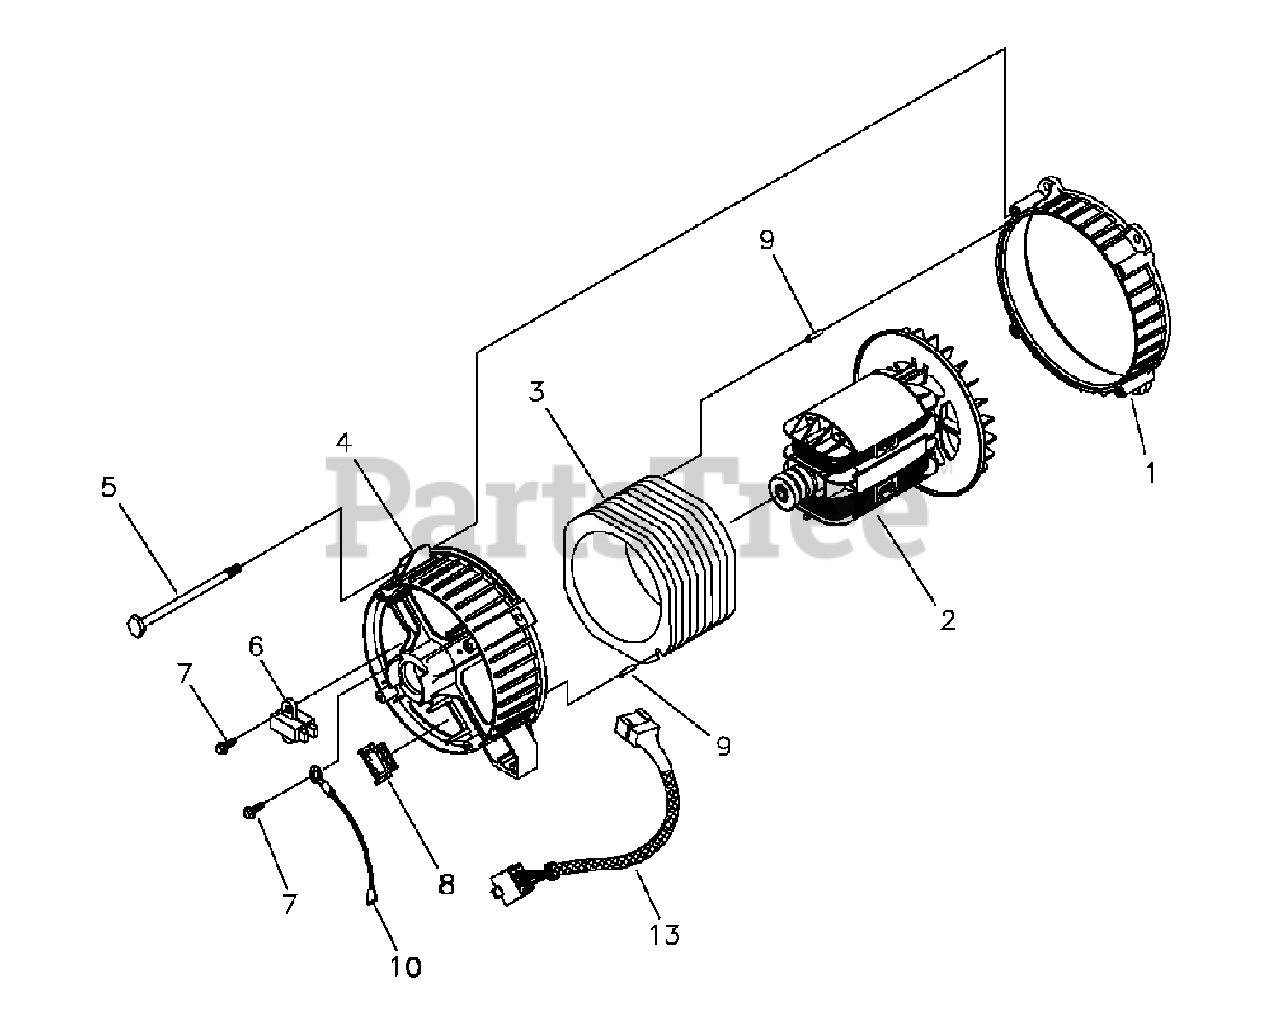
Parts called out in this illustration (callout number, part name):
1	ADAPTER,Mounting,Alternator
4	RBC,with O-Ring (p/n 189197GS)
5	HHCS,M6 - 1.0 x 140 SEMS
6	ASSY,Holder,Rectifier/Brush
7	TAPTITE,M5 - 0.8 x 16
8	RECEPTACLE,6 pin
9	PIN,Roll,4mm x 10
10	ASSY,Wire,Ground
13	HARNESS,Wire,Power
